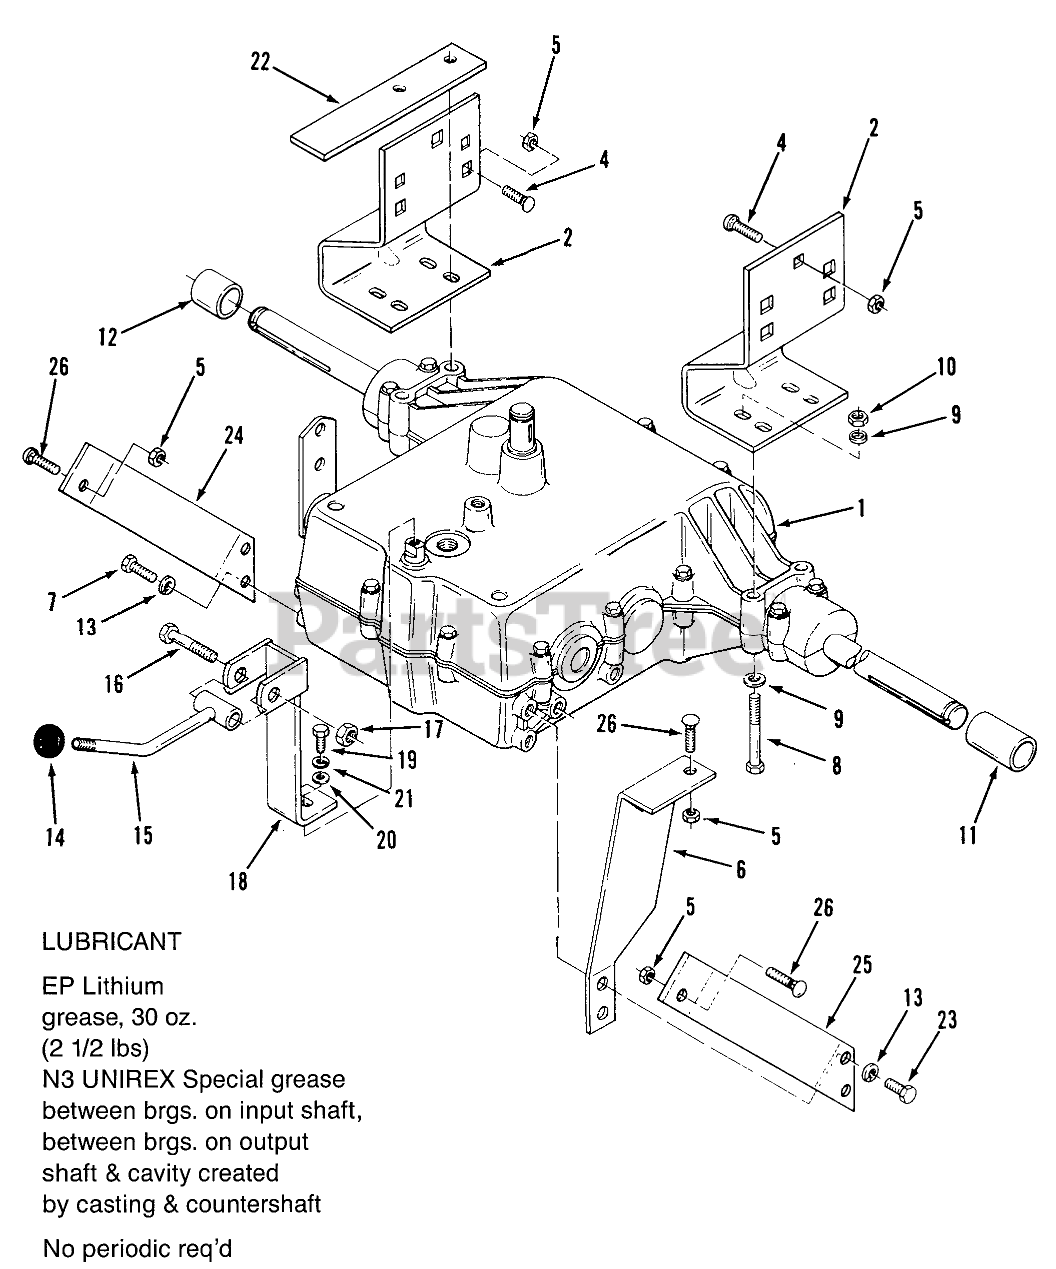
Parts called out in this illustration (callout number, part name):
1	Transmission-5-Speed Peerless Model 801-026
2	BRKT-TRANS MOUNT R
4	CARRIAGE BOLT -4
5	Nut
6	TORQUE STRAP
7	Screw
8	HHCS
9	WASHER 5/16 SAE
10	Nut
11	SPACER-AXLE LH
12	SPACER-AXLE RH
13	Lockwasher
15	ASSY-UPPER SHIFT ROD
16	Bolt
17	NUT
18	ASSY LEVER R
19	Bolt-12 Point-5-Speed
20	WASHER
21	Washer
22	Brake Stop Bar
23	Bolt
24	TORQUE STRAP RH
25	TORQUE STRAP LH
26	Bolt
